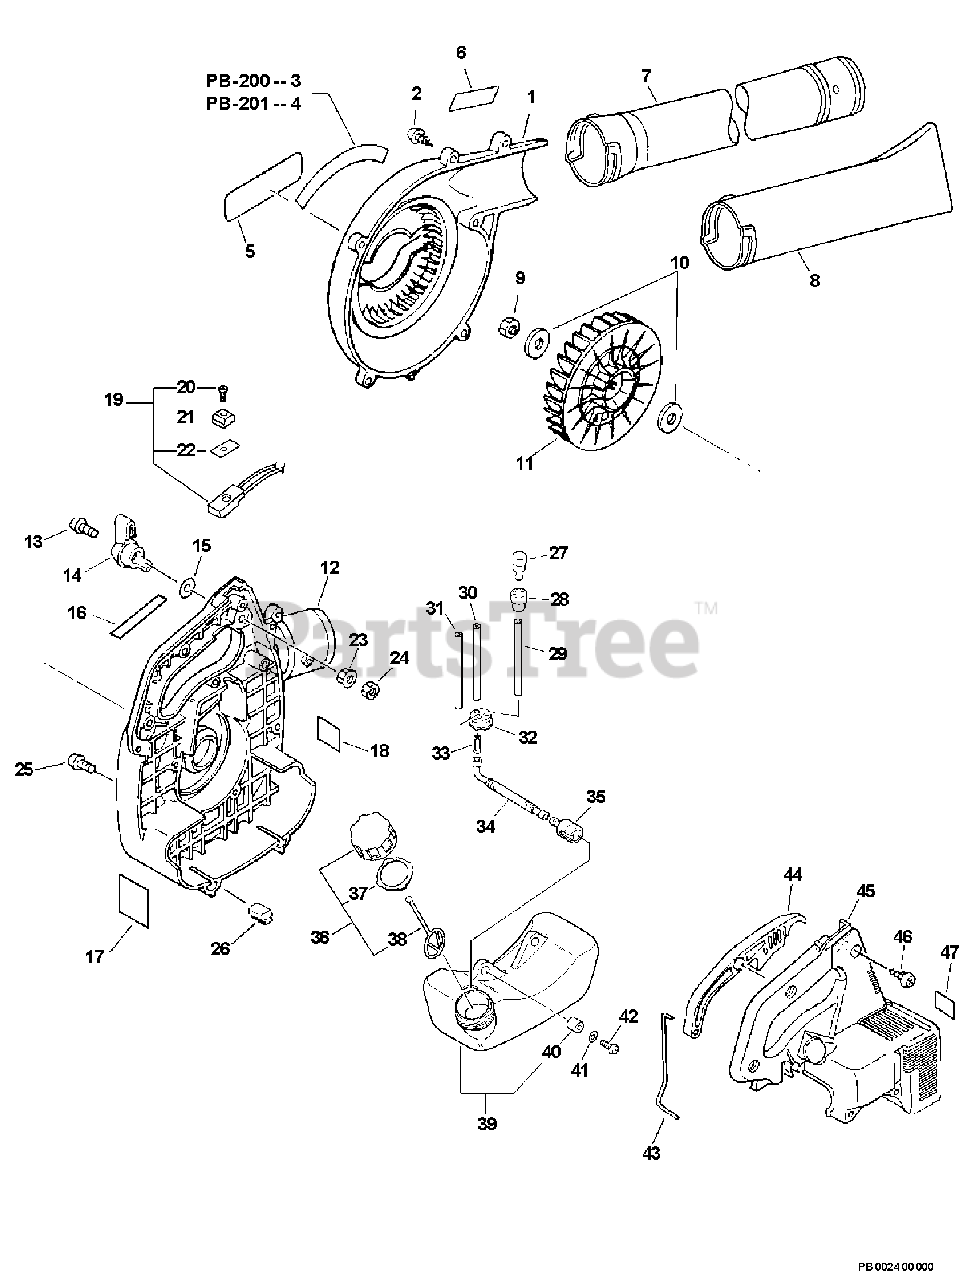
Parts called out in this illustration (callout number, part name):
1	COVER, FAN - LEFT
2	SCREW - 5X20 -- TAPPING
3	LABEL - MODEL PB-200
4	LABEL - MODEL PB-201
5	LABEL - ECHO
6	LABEL - NOISE
7	TUBE, BLOWER - STRAIGHT
8	TUBE, BLOWER - NOZZLE
10	WASHER - 8
12	COVER, FAN - RIGHT
13	SCREW - 5X25
14	LEVER, THROTTLE - ORANGE
15	WASHER - 5
16	LABEL - CAUTION
17	LABEL - CAUTION -- SPANISH
18	LABEL - CAUTION
19	IGNITION SWITCH ASSY
20	SCREW - 3X10
21	KNOB, SWITCH - ORANGE
22	COVER, SWITCH - STOP
23	NUT - 5 -- FLANGE
25	SCREW - 4X22
27	VENT, FUEL TANK
28	COVER, VENT
29	PIPE - 3X5X70 -- BLACK
30	PIPE - 3X5X90 -- BLACK
31	PIPE - 3X6X90 -- CLEAR
32	GROMMET
33	CONNECTOR, PIPE
34	PIPE, FUEL - CORRUGATED
35	FILTER, FUEL
36	CAP ASSY - ORANGE
37	GASKET, CAP
38	CONNECTOR, CAP
39	FUEL TANK ASSY
41	WASHER - 5
42	SCREW - 5X16
43	ROD, THROTTLE
44	TRIGGER, THROTTLE - ORANGE
45	COVER, ENGINE - GRAY
46	SCREW - 5X20 -- TAPPING
47	LABEL - HOT SURFACE
